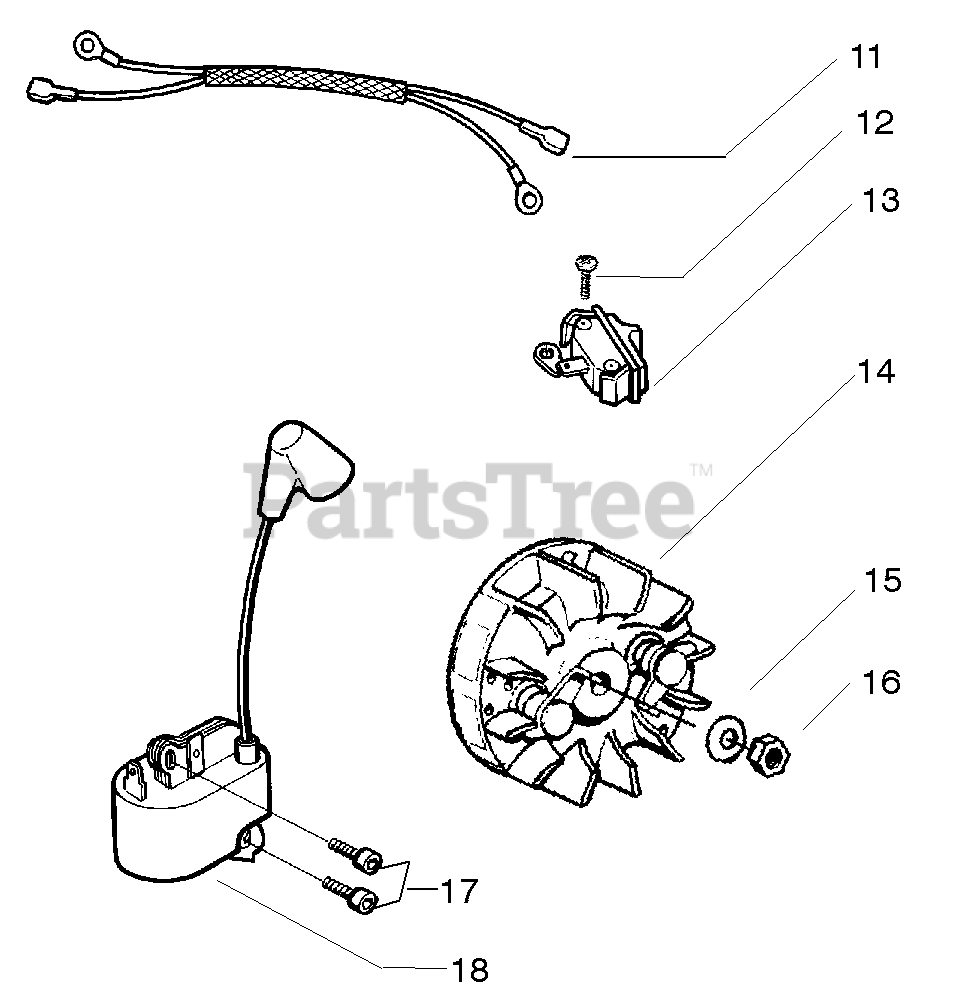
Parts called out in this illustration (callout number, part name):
11	Assy-Leadwire Harness
13	Switch-Ignition
14	Assy. -Flywheel
15	Washer-Flywheel
18	Module - Ignition
